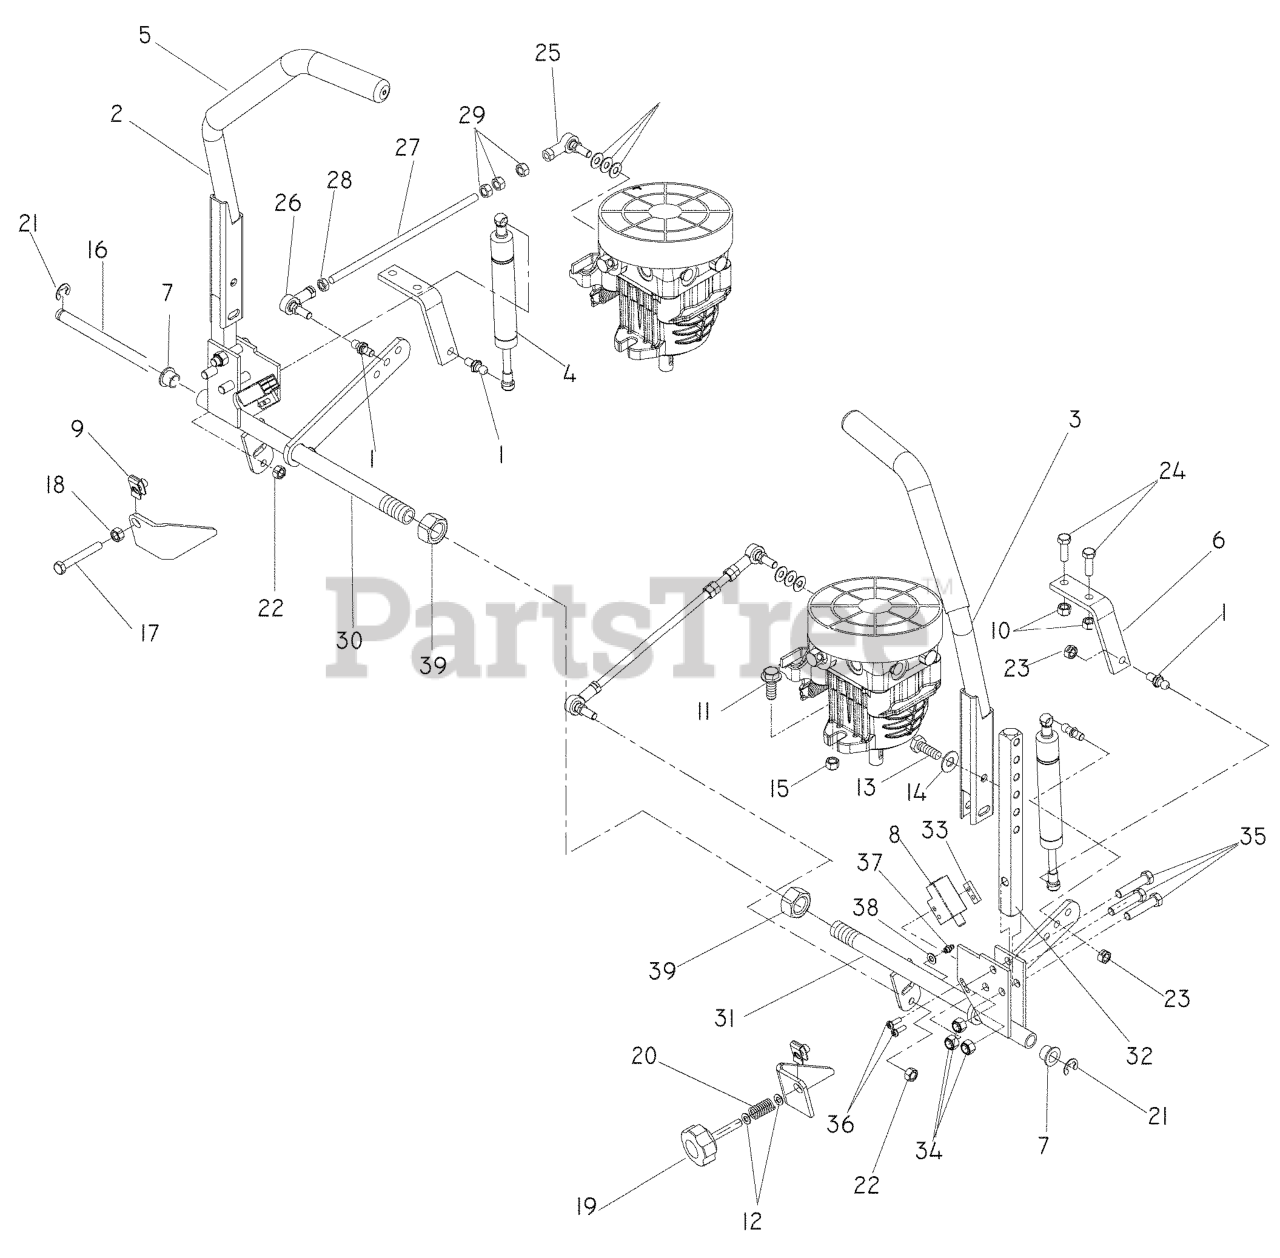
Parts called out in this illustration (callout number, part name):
1	STUD.BALL.10MM
2	ASSEMBLY, DRIVE LEVER RT
3	ASSEMBLY, DRIVE LEVER LT
4	DAMPENER
5	GRIP - DRIVE LEVER 12"
6	DAMPENER BRACKET
8	SWITCH, INTERLOCK
9	U-CLIP 5/16-18 NUT RETAINER
10	NUT 5/16 NYLOC
11	4CS 3/8C X 1 SERRATED HEAD
12	WASHER 5/16 FLAT
13	HCS 3/8-16X1.GRD.5.ZD
14	WASHER, 3/8 DISC SPRING SPEC
15	NUT 3/8C CENTERBLOCK
16	CONTROL SHAFT
17	HCS 5/16-18X1-3/4 TPBLT
18	NUT 5/16C HEX
19	ADJUSTMENT KNOB
20	COMPRESSION SPRING
21	E-RING 1/2 (2 2)
22	NUT 5/16F NYLOC
23	NUT 5/16C CENTERLOCK
24	HCS 5/16C X 1
25	SPHERICAL ROD END, RH
26	SPHERICAL ROD END, LH
27	PUMP CONTROL LINK
28	NUT 5/16F LEFTHAND
30	CONTROL, RT
31	CONTROL, LT
32	CONTROL ARM
33	TAPPED PLATE
34	NUT 3/8-16 NYLOC
35	HCS 3/8-16 X 1 3/4 GR5
36	SCREW #10-24 X 5/8
37	ZERK
39	NUT 3/4 X 16 HEX CTR
